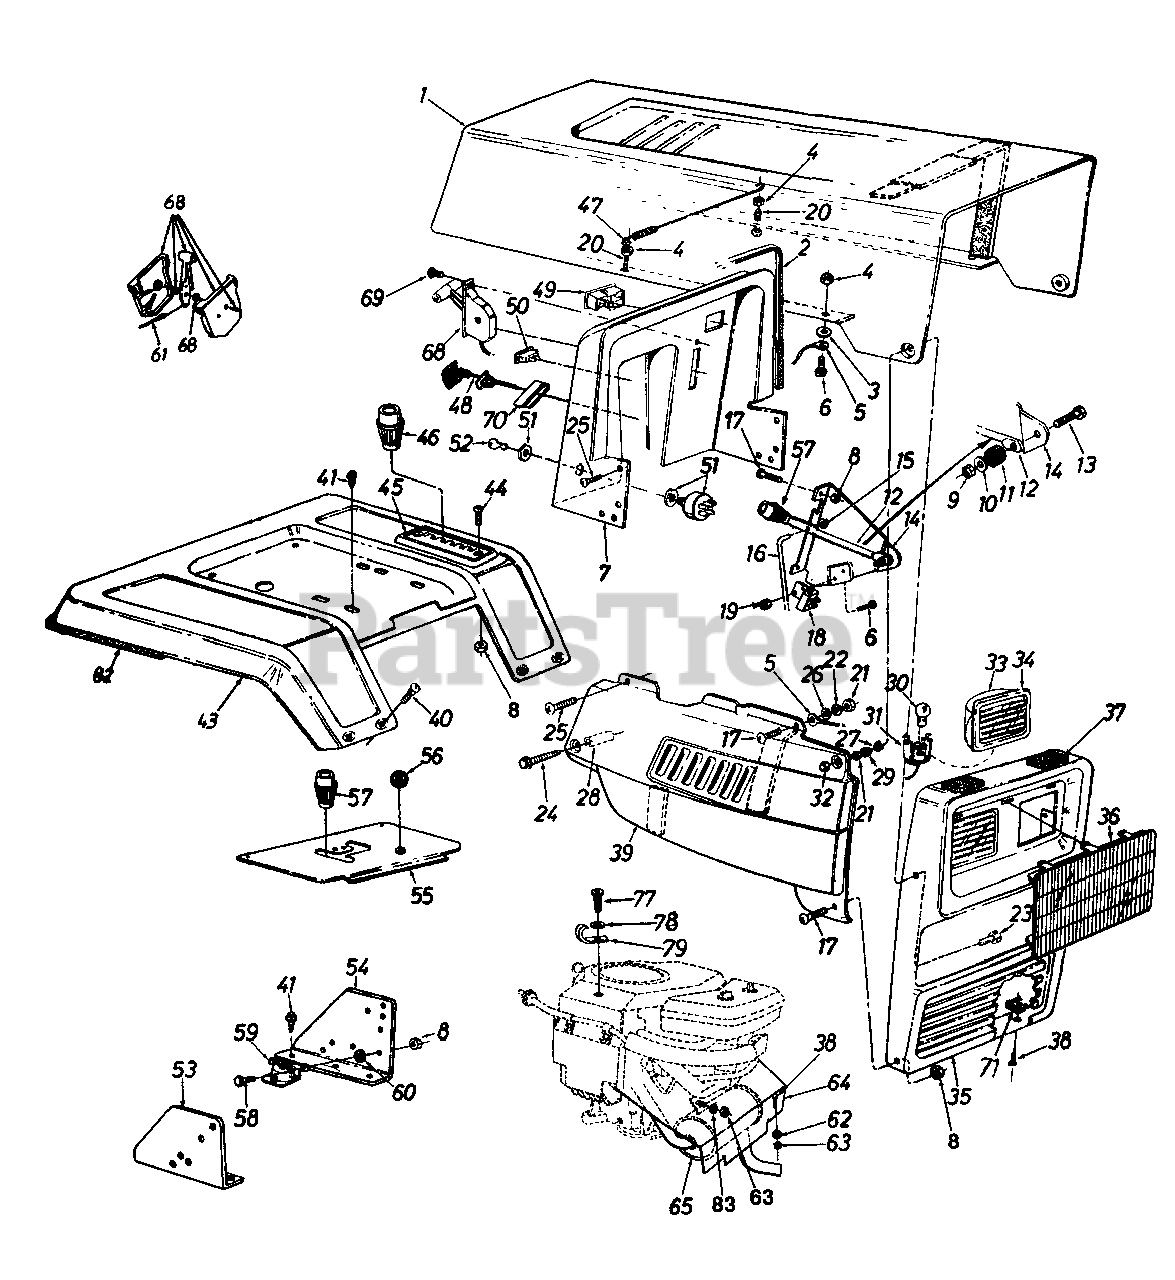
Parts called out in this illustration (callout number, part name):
3	Fl-Wash. .20" I.D. x .41" O.D.
4	Hex Sems Nut #10-24 Thd.
5	Hood Stop
6	Truss Mach. Scr. #10-24 x .5" Lg.
9	Hex L-Nut 1/4-20 Thd.
10	Fl-Wash. .281" I.D. x .73" O.D.
11	Rubber Washer
12	PTO Lever
13	Hex Bolt 1/4-20 x 1.25" Lg.
16	Deck Control Rod
17	Truss Mach. Scr. 1/4-20 x .5" Lg.
18	Safety Switch
19	Hex Sems Nut #10-24 Thd.
20	Hex Bolt 10-24 x 1.0" Lg.
21	Hex Nut 1/4-20 Thd.
22	L-Wash. 1/4" I.D.
23	Hex Bolt 1/4-20 x .88" Lg.
24	Hex Wash. TT-Tap Scr. 1/4-20 x 1.75" Lg.
25	Hex TT-Tap Scr. 1/4-20 x .75" Lg.
26	Fl-Wash. .25" I.D. x .62"
27	Spr. Wash. .39" I.D. x .62"
28	Spacer.26" I.D. x .375"
29	Shld. Spacer .375" Dia. x .125" Lg.
30	Lamp
31	Socket
32	Acorn Nut 1/4-20 Thd.
33	Headlight Housing
34	Headlight Lens
37	Foam Strip
38	Hex Bolt 5/16-18 x .75" Lg.
41	Hex Wash AB-Tap Scr 5/16 x .75" Lg.
45	6-Speed Selector Plate
46	Shift Knob
47	Hood Spring
48	Choke Control 46" Lg.
49	Ammeter
50	Light Switch
51	Ignition Switch
52	Ignition Key
56	Ball Knob
57	Knob - Blade Clutch
58	Hex Bolt 1/4-20 x .5" Lg
59	Solenoid
60	Ext. L-Wash. 1/4" I.D.
61	Throttle Wire 35" Lg.
62	L-Wash. 5/16" I D,
63	Hex Nut 5/16-18 Thd
64	Front Heat Shield
65	Muffler
68	Throttle Control Box Ass'y.
69	Truss Mach. AB-Tap Scr. #10 x .5" Lg.
70	Retainer Clip
71	U-Nut 5/16-18 Thd.
77	Truss Mach. B-Tap Scr. #10 x .5" Lg.
78	Fl-Wash. .188" I.D. x .438" O.D.
79	Clamp
82	Trim Strip 81" Lg.
83	Spec. L-Wash. 5/16" I.D.
